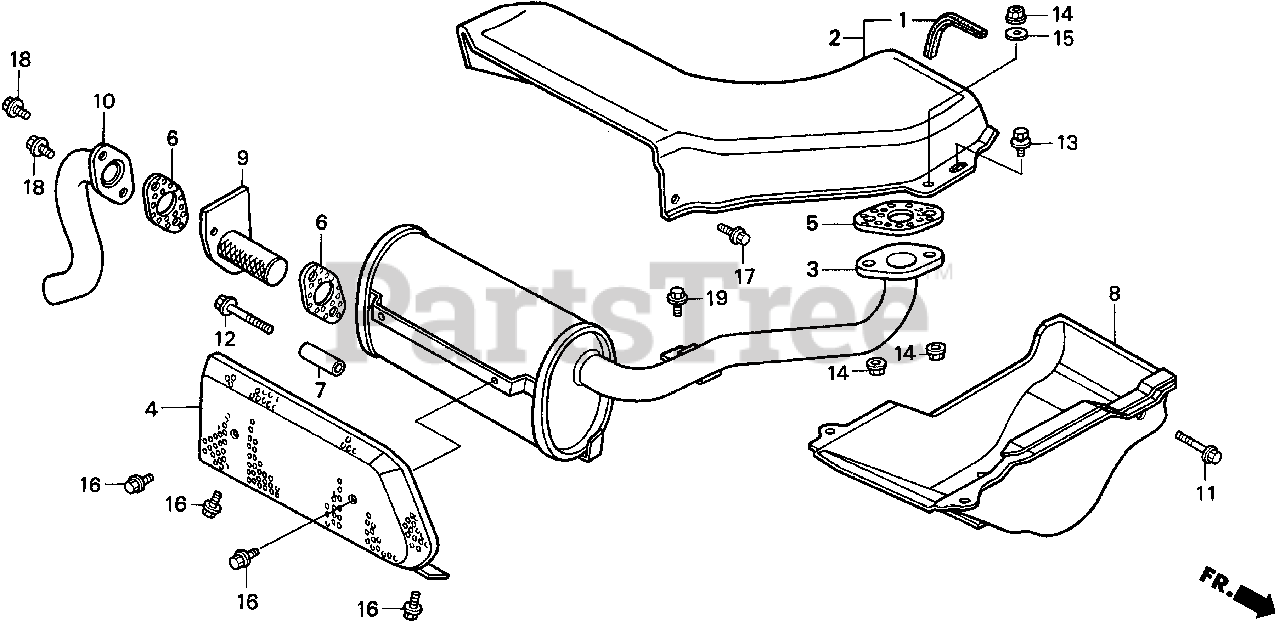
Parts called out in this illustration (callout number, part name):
1	RUBBER, PROTECTOR
2	PROTECTOR ASSY., HEAT (UPPER)
4	PROTECTOR, MUFFLER
5	GASKET, EX. PIPE Use up to Engine SN 2949254.
5	GASKET, EX. PIPE (WACKER)
6	GASKET, TAIL PIPE
7	COLLAR, MUFFLER JOINT
8	PROTECTOR, HEAT (LOWER)
9	ARRESTER, SPARK (NOT AVAILABLE)
10	PIPE, TAIL
11	BOLT, FLANGE (6X12) (CT200)
12	BOLT, FLANGE (8X55)
13	BOLT-WASHER (6X12)
14	NUT, FLANGE (8MM)
15	WASHER, PLAIN (8MM)
16	BOLT, FLANGE (6X12)
17	BOLT, FLANGE (6X12)
18	BOLT, FLANGE (6X16)
19	BOLT, FLANGE (8X16)
